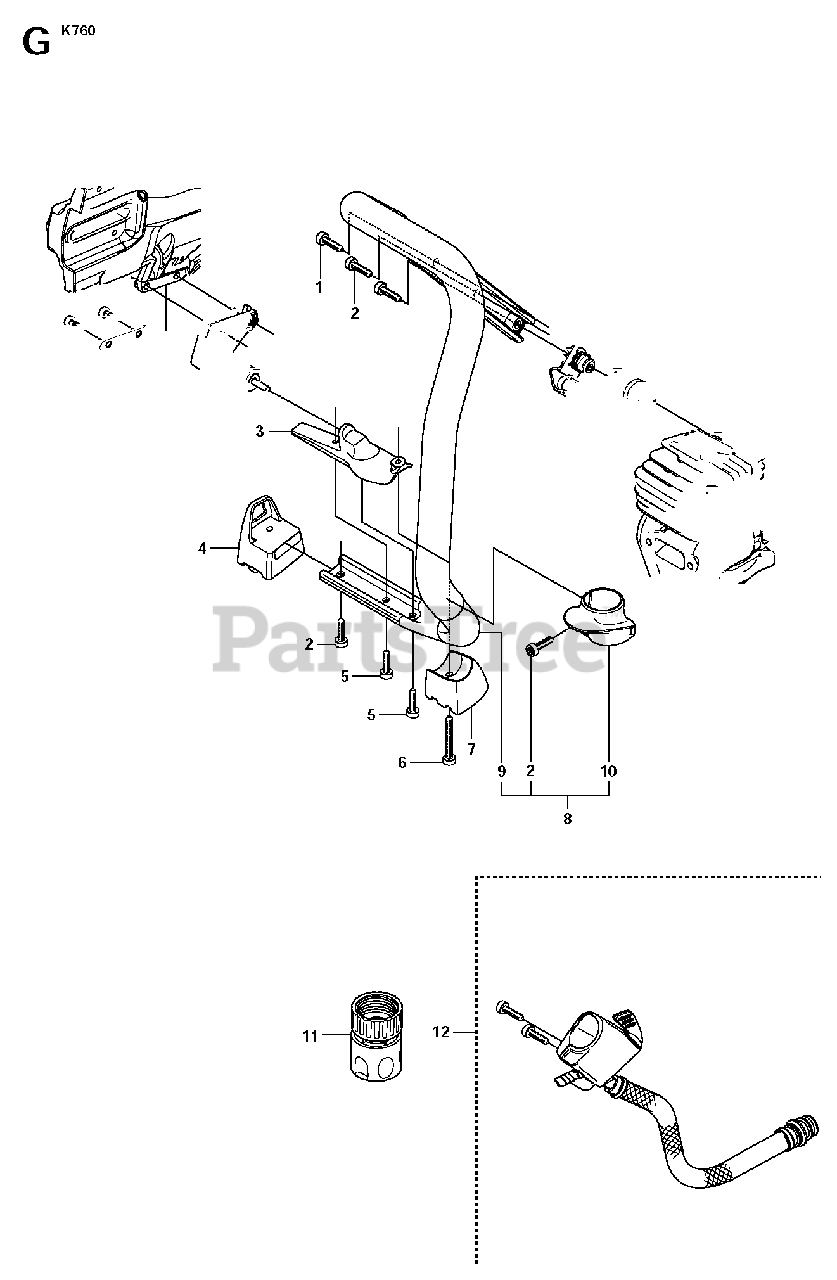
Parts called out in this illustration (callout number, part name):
1	SCREW ITXSCM
2	SCREW ITXSCT
3	SPRING RETAINER
4	GROUND SUPPORT
5	SCREW ITXSCM
6	SCREW ITXSCM
7	GROUND SUPPORT
8	HANDLEIncl. 4, 9-10
9	FRONT HANDLE
11	COUPLERUSA, Canada
